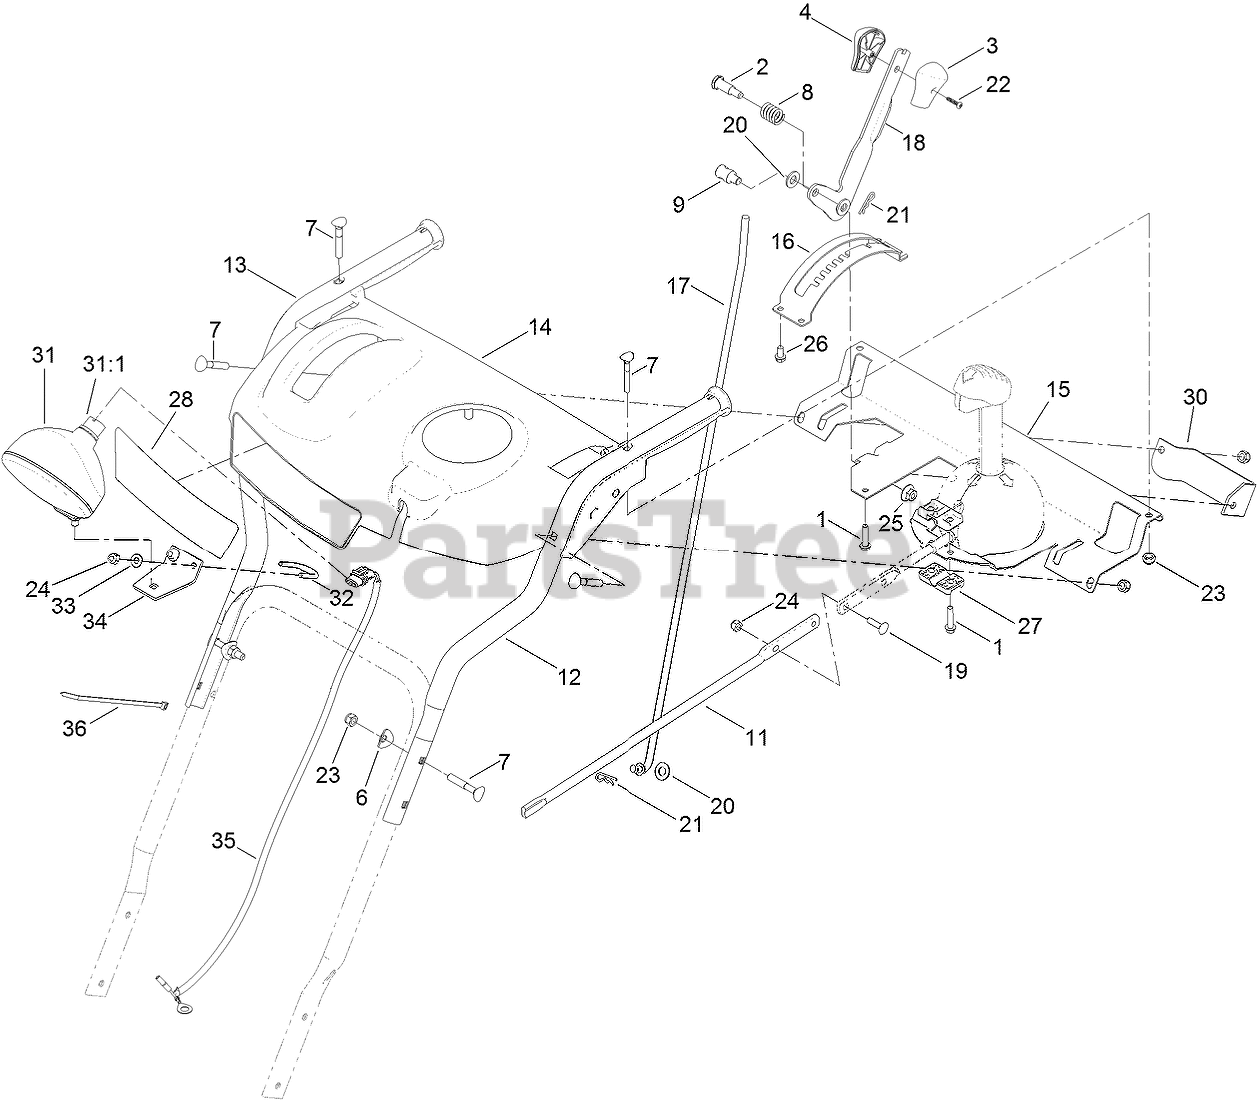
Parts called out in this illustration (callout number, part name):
1	SCREW-PLASTITE
2	SCREW-SHOULDER
3	KNOB-SHIFT, LH
4	KNOB-SHIFT, RH
6	WASHER
7	SCREW-HANDLE
8	SPRING-COMPRESSION
9	TRUNNION-ROD
11	ROD-CHUTE, FRONT
12	HANDLE-UPPER, LH
13	HANDLE-UPPER, RH
14	PANEL-CONTROL, MASTER
15	SUPPORT-PANEL, CONTROL
16	MOUNT-SELECTOR, SPEED
17	ROD-SELECTOR, GEAR
18	SELECTOR-SPEED
19	SCREW-CARR
20	WASHER-FLAT
21	PIN-COTTER
22	SCREW-PPH
23	NUT-LOCK, NI
24	NUT-LOCK, NI
25	NUT-HF
26	SCREW-PLASTITE
27	SUPPORT-ROD
28	DECAL-CONTROL PANEL
30	PLATE-SUPPORT, SHIFT
31	HEADLAMP ASM
31:1	LAMP-12 VOLT
32	CLAMP
33	WASHER-FLAT
34	BRACKET-LIGHT
35	HARNESS-WIRE
36	TIE-CABLE
